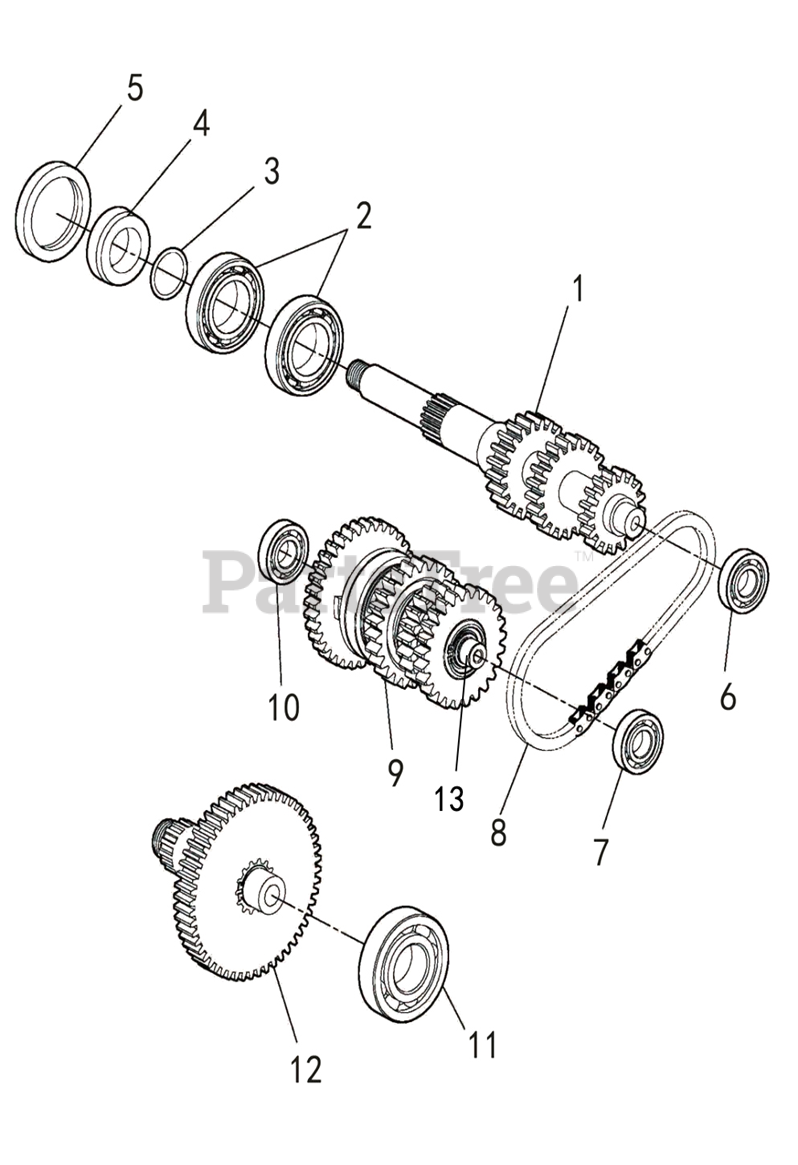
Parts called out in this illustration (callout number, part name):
1	TRANSMISSION MAIN SHAFT
2	BEARING 6006C3
3	O-RING 26.1X2.4
4	SECONDARY CVT BUSHING
5	OIL SEAL 42X55X8
6	BEARING 6203
7	BEARING 6202
8	TOOTH SHAPED CHAIN FOR R GEAR
9	COUNTER SHAFT ASSEMBLY
10	BEARING 6203DLA8
11	BEARING 6303
12	X DRIVESHAFT ASSEMBLY
13	COUNTER SHAFT
